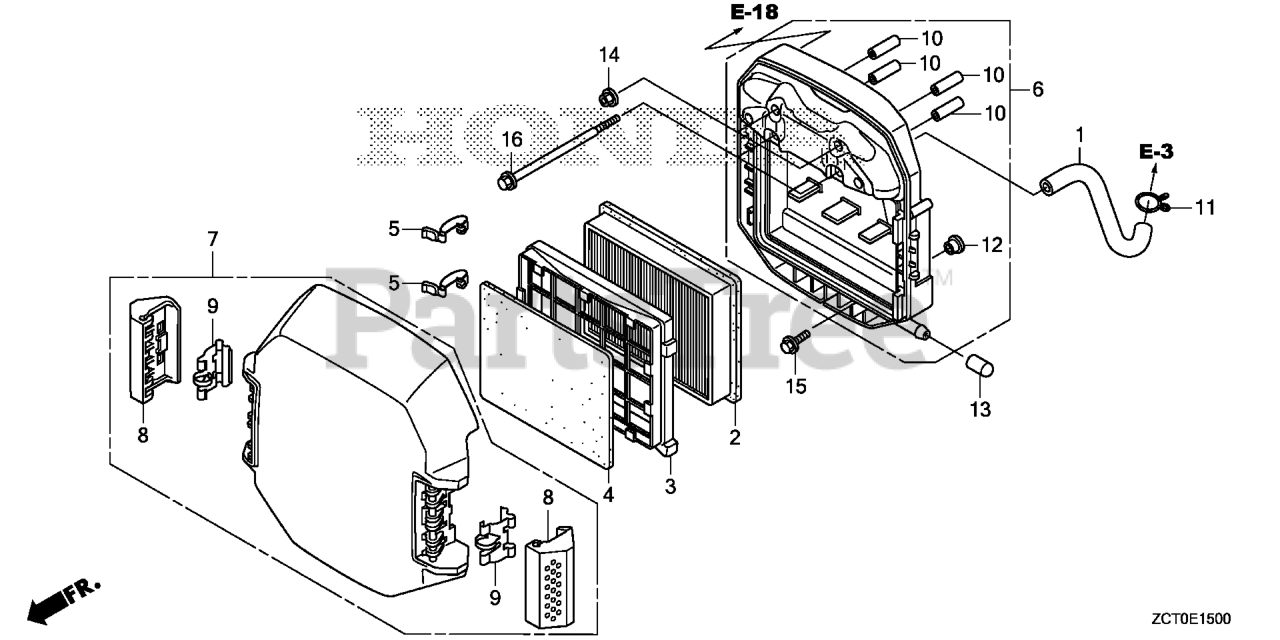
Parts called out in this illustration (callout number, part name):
1	TUBE, BREATHER
2	ELEMENT, AIR CLEANER
3	HOLDER, ELEMENT
4	FILTER (OUTER)
5	CLIP, AIR CLEANER
6	HOUSING, AIR CLEANER
7	COVER, AIR CLEANER
8	KNOB, AIR CLEANER COVER
9	SPRING, AIR CLEANER HOUSING COVER
10	COLLAR, AIR CLEANER
11	CLIP, BREATHER TUBE
12	COLLAR, FAN COVER
13	CAP, SEALING
14	NUT, FLANGE (6MM)
15	BOLT, FLANGE (6X16) Use from Engine SN 2056820.
16	BOLT, FLANGE (6X110)
